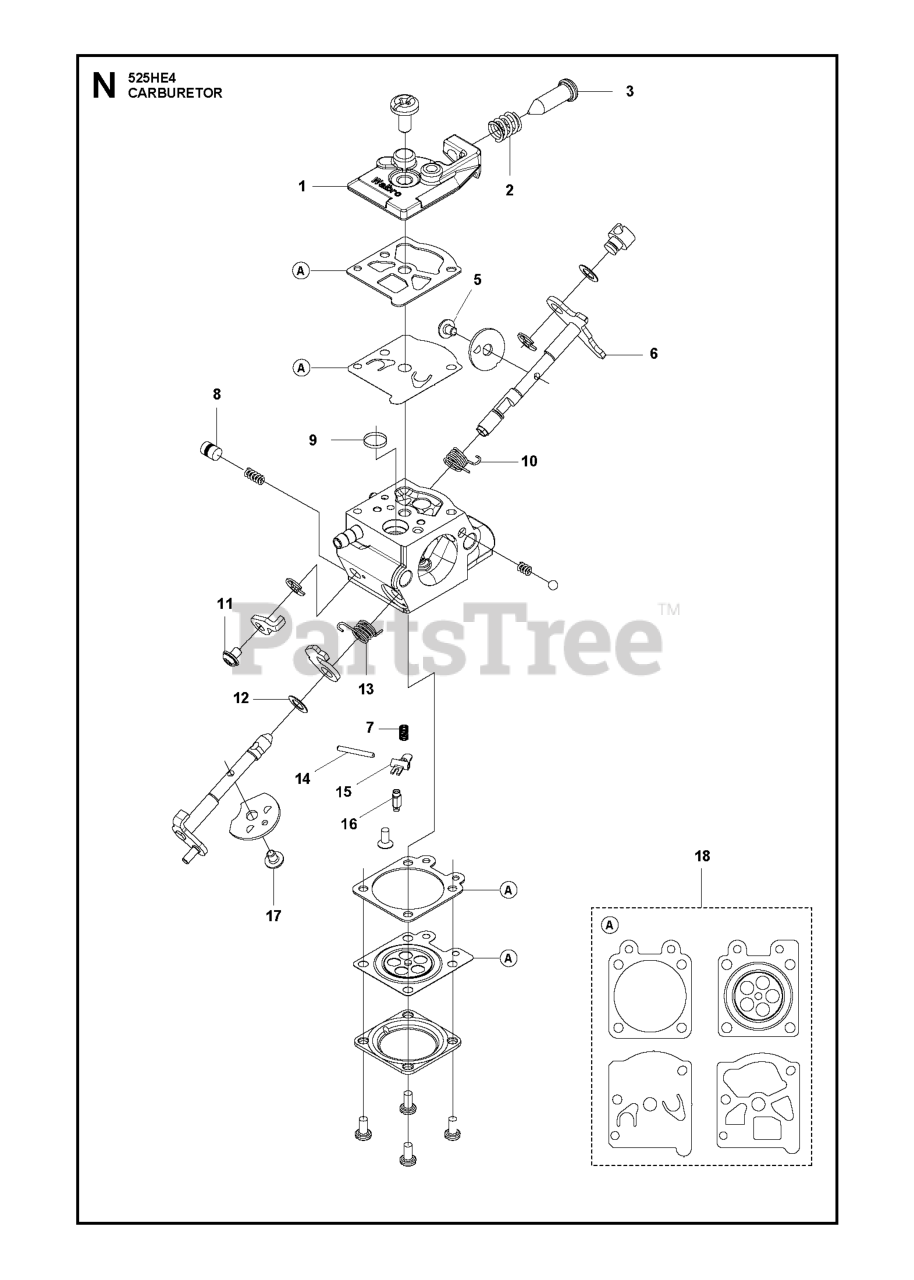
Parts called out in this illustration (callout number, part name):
1	COVER PUMP
3	SCREW, IDLE
6	SHAFT ASSEMBLY,THROTTLE
8	PISTON ASSY
9	SCREEN
16	VALVE INLET
18	GASKET KIT
